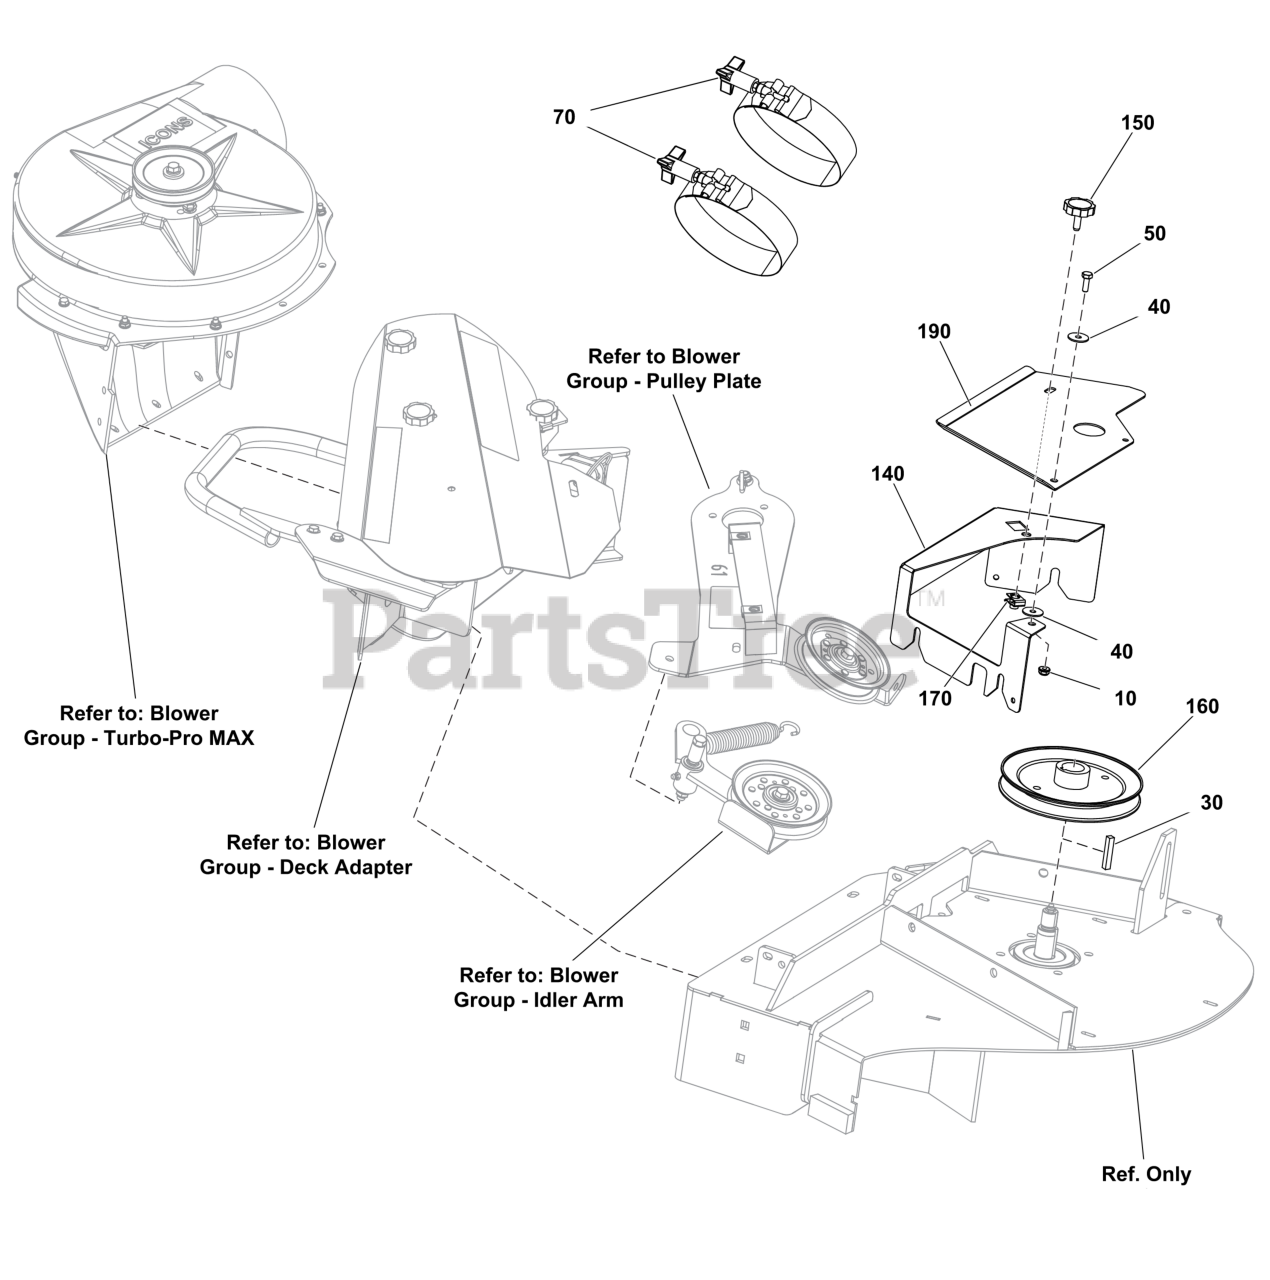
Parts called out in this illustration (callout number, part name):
30	KEY 1/4 SQ X 1 1/2
40	WASHER, 1/4 FENDER
50	BOLT, 1/4-20 X 3/4" G
140	GUARD, Pulley
150	KNOB, 5/616-18 X 1
160	PULLEY, Spindle
170	NUT, SPEED, 5/16-18 L
190	SHIELD, Belt
